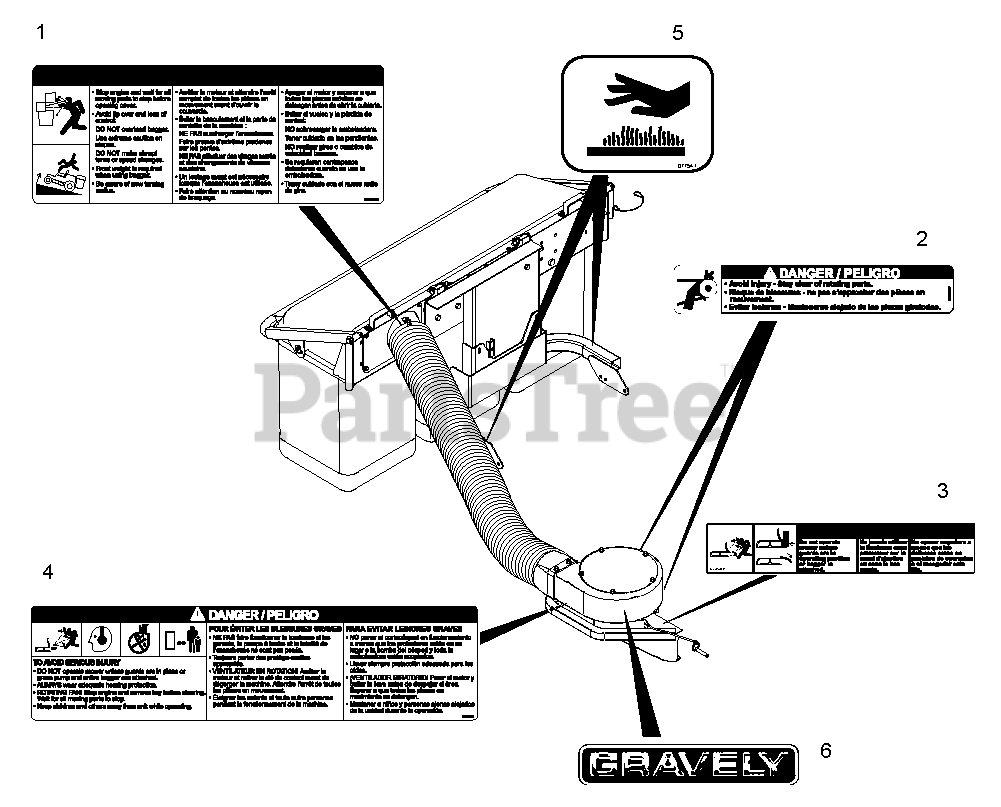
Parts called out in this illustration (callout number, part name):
1	Decal-Warning, Bagger Cover
2	Decal, Danger
3	Decal, Warning
4	Decal-Caution, Grass Pump
5	Decal, Hot Surface
6	Decal, Gravely
